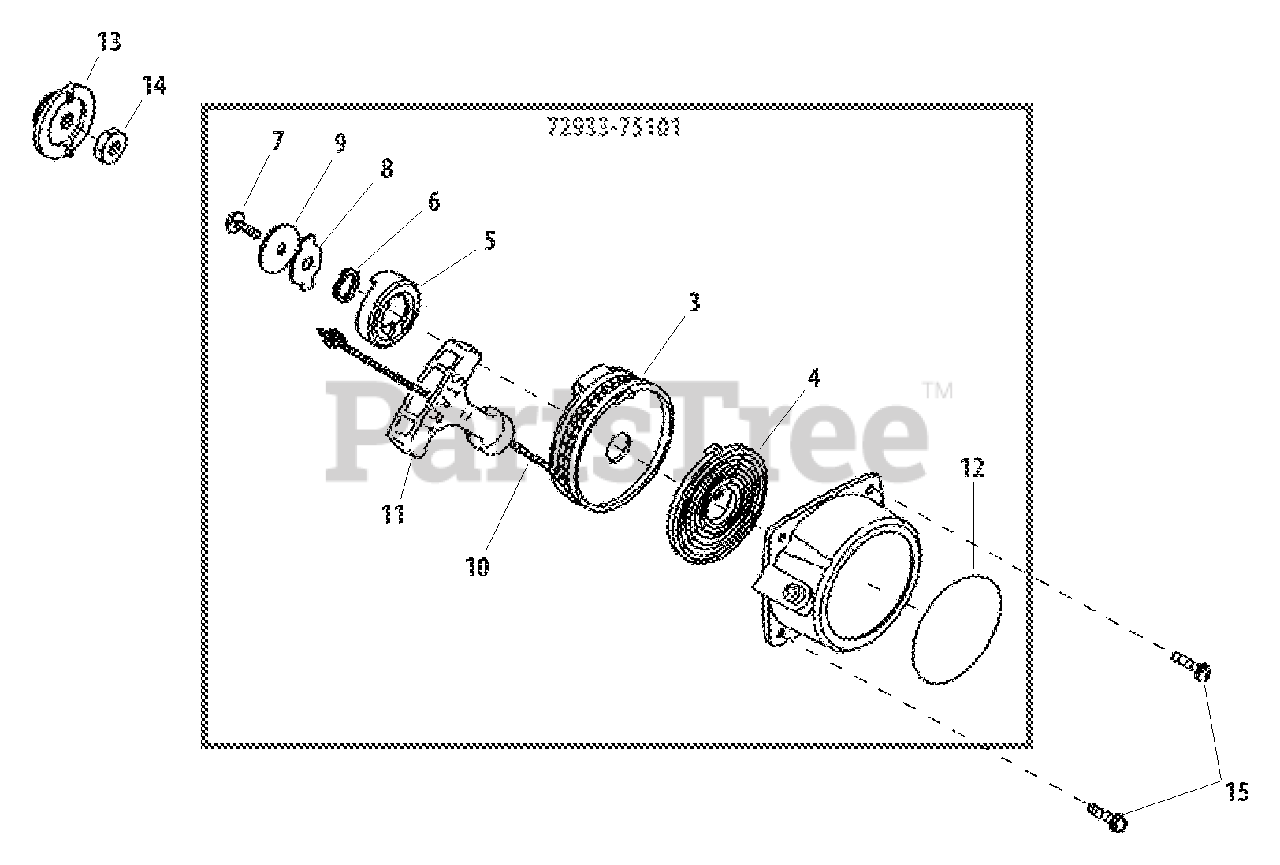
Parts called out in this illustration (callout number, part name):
3	REEL, ROPE
4	SPRING, REWIND
5	PAWL, STARTER
6	WASHER - SPRING
7	SCREW - 5
8	RETAINER
9	WASHER - 5
10	ROPE, STARTER
11	GRIP, STARTER
12	LABEL - IDENTIFICATION
13	PAWL
14	NUT - 8
15	SCREW - 4X12
72933-75101	STARTER ASSY
